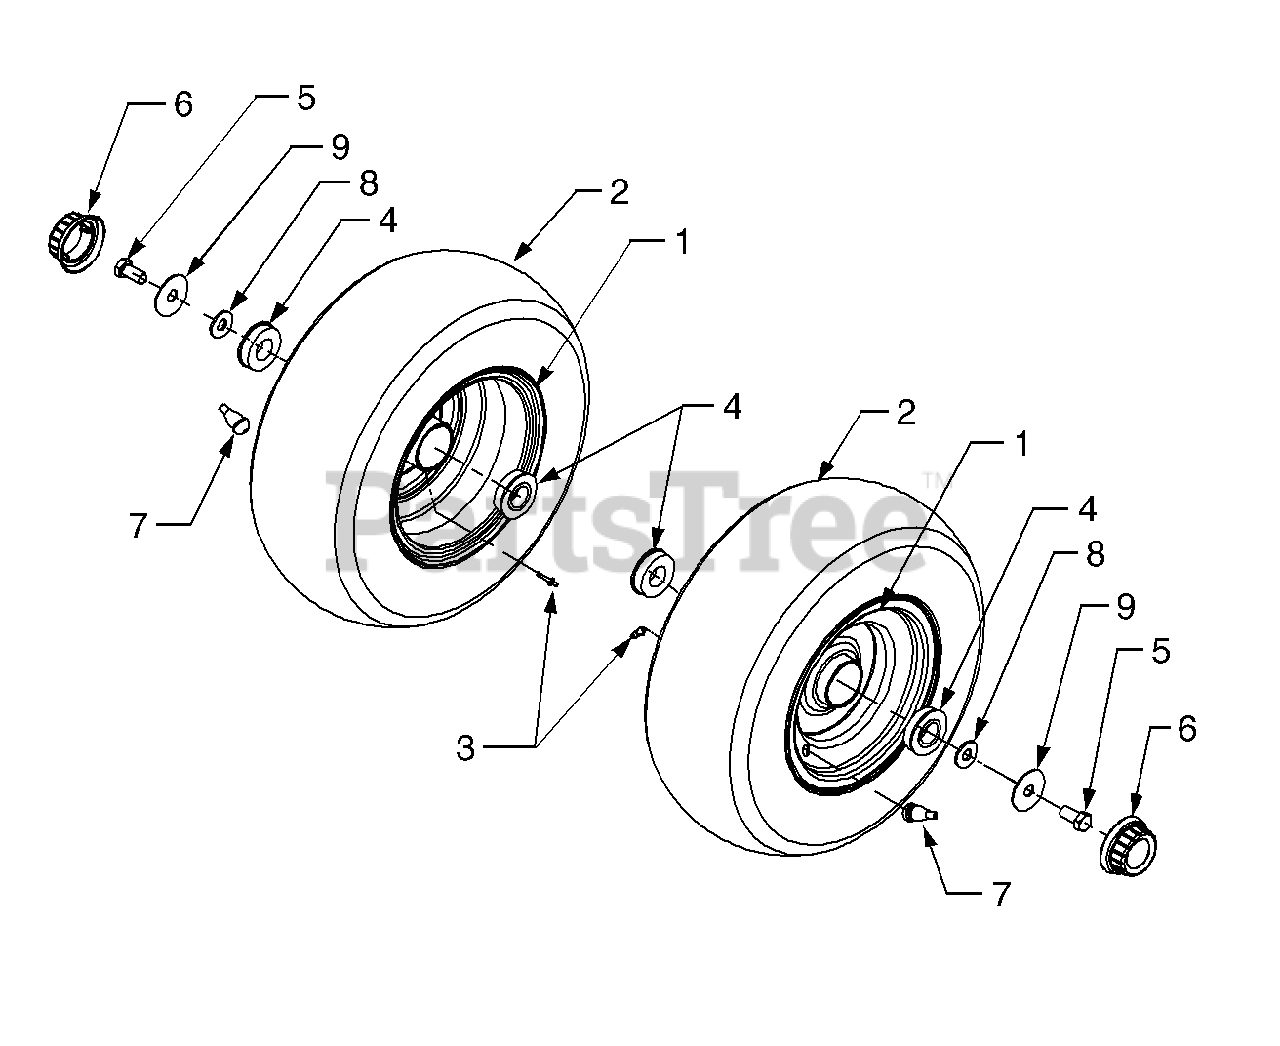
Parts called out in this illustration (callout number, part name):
1	Rim Assembly, Wheel
2	Tire, Turf, 16 x 6.5 x 8.0
3	Lube Fitting
4	Bearing, Ball
5	Screw, Hex Cap, 1/2-13 x 1.0 GR5
6	Hubcap
7	Valve, Tubeless Air
8	Washer, Flat, .531 x 1.25 x .1
9	Washer, Flat, .535 x 1.92 x .060
